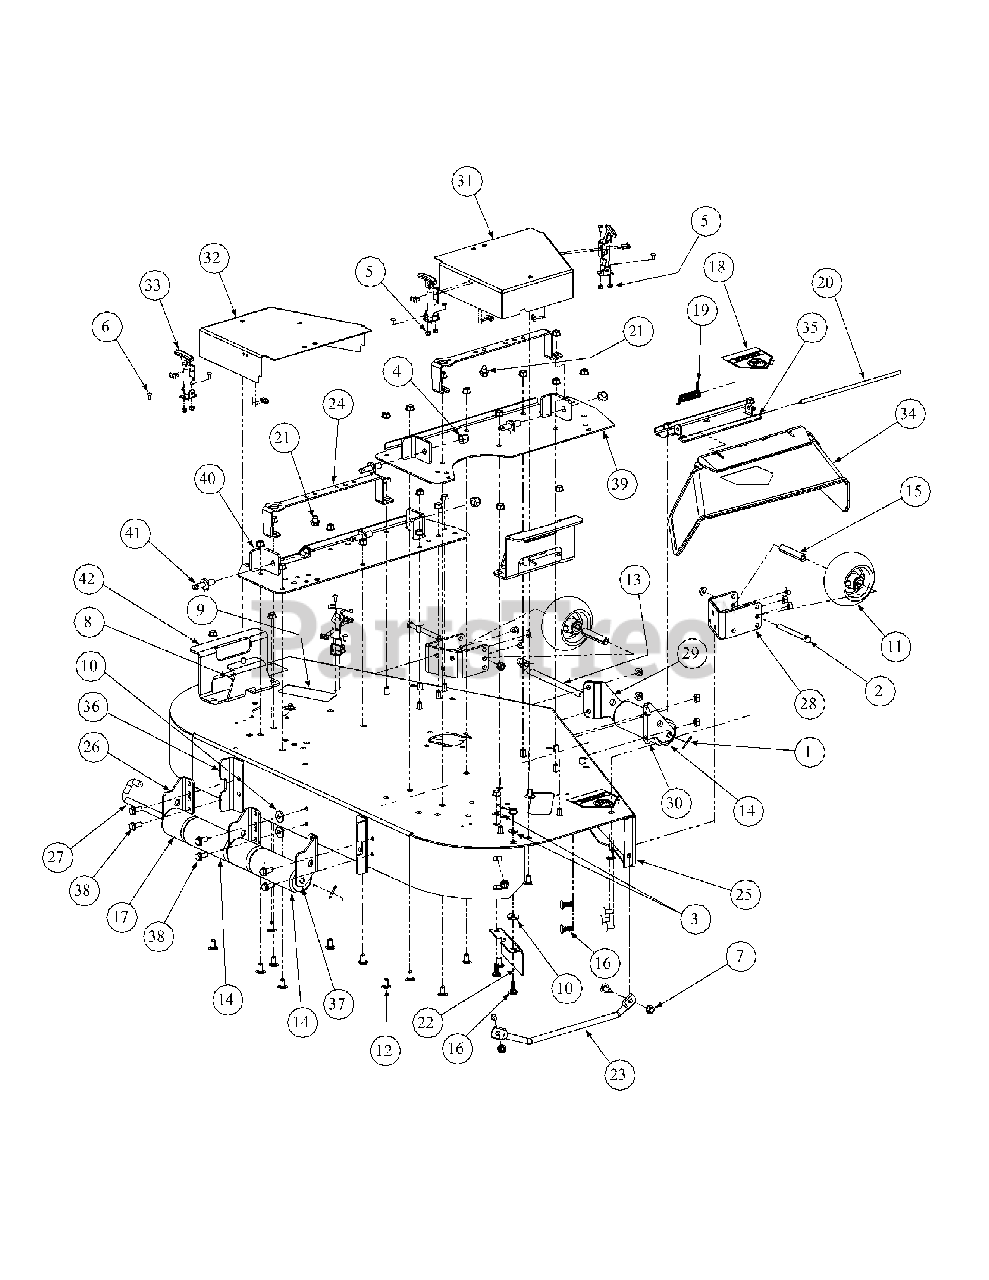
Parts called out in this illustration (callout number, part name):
1	Cotter Pin, .125 Dia x 1.0
2	Hex Head Cap Screw, 3/8-16 x 4.00
3	Washer, 3/8 Zinc
4	Nut, 1/2-13, Nylon Insert
5	Nut, 10-32, Nylon Insert
6	Phillips Head Machine Screw, 10-32 x 1/2
7	Nut, 3/8-16, Hex Flange Lock
8	Decal, Rotating Blade
9	Decal, Warning Shield Missing
10	Idler Washer
11	Wheel, 5.00 Dia
12	Carriage Bolt, 3/8-16 x .75
13	Roller Pin, 1/2 Dia x 7.31
14	Front Roller
15	Wheel Spacer
16	Carriage Bolt, 3/8-16 x 1.00
17	Grass Catcher Roller
18	Decal, Danger Hands & Feet
19	Torsion Spring, 0.4 ID x 2.16
20	Deflector Chute Rod
21	Self Tapping Screw, 3/8-16 x 0.500
23	Finger Guard
24	Belt Cover Support
25	48" Fab Deck Assembly
26	Grass Catcher Roller Bracket
27	Grass Catcher Roller Rod
28	Front Anti SCalp Wheel Bracket
31	Right Hand Belt Cover Weldment
31	Right Hand Belt Cover
32	Left Hand Belt Cover Weldment
32	Left Hand Belt Cover
33	T-Handle Draw Latch
34	Chute Deflector
35	Chute Deflector Bracket
36	Deck Sway Bracket
37	Grass Catcher Roller Bracket
38	Self Tapping Screw, 3/8-16 x 0.875
39	Right Hand Lift Plate Weldment
40	Left Hand Lift Plate Weldment
41	Deck Lift Pin, 7/16 Dia x 1.20
42	Handle Cover Bracket Deck Weldment
